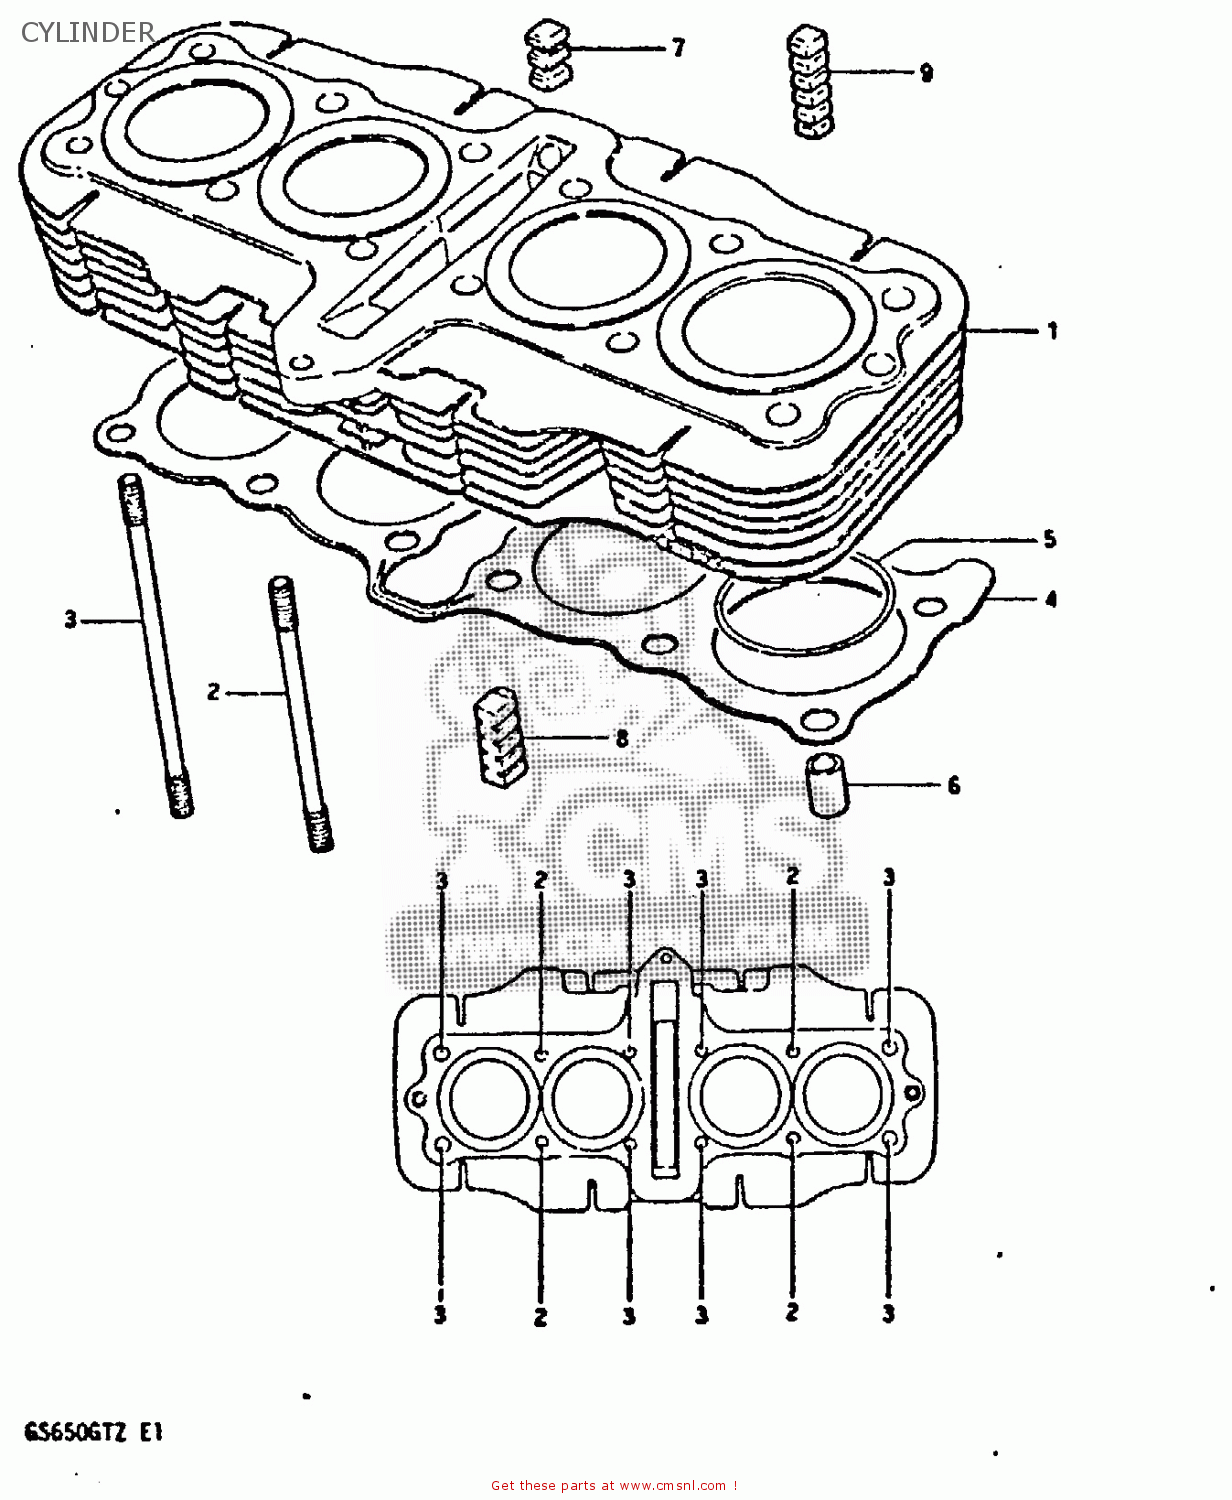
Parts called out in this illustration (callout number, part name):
1	CYLINDER
2	BOLT,STUD
3	BOLT,STUD
4	GASKET,CYLINDER (MCA)
5	O RING(D:2,ID:61)
6	PIN
7	PAD,CYLINDER
8	PAD,CYLINDER
9	PIN,EXHAUST VALVE
